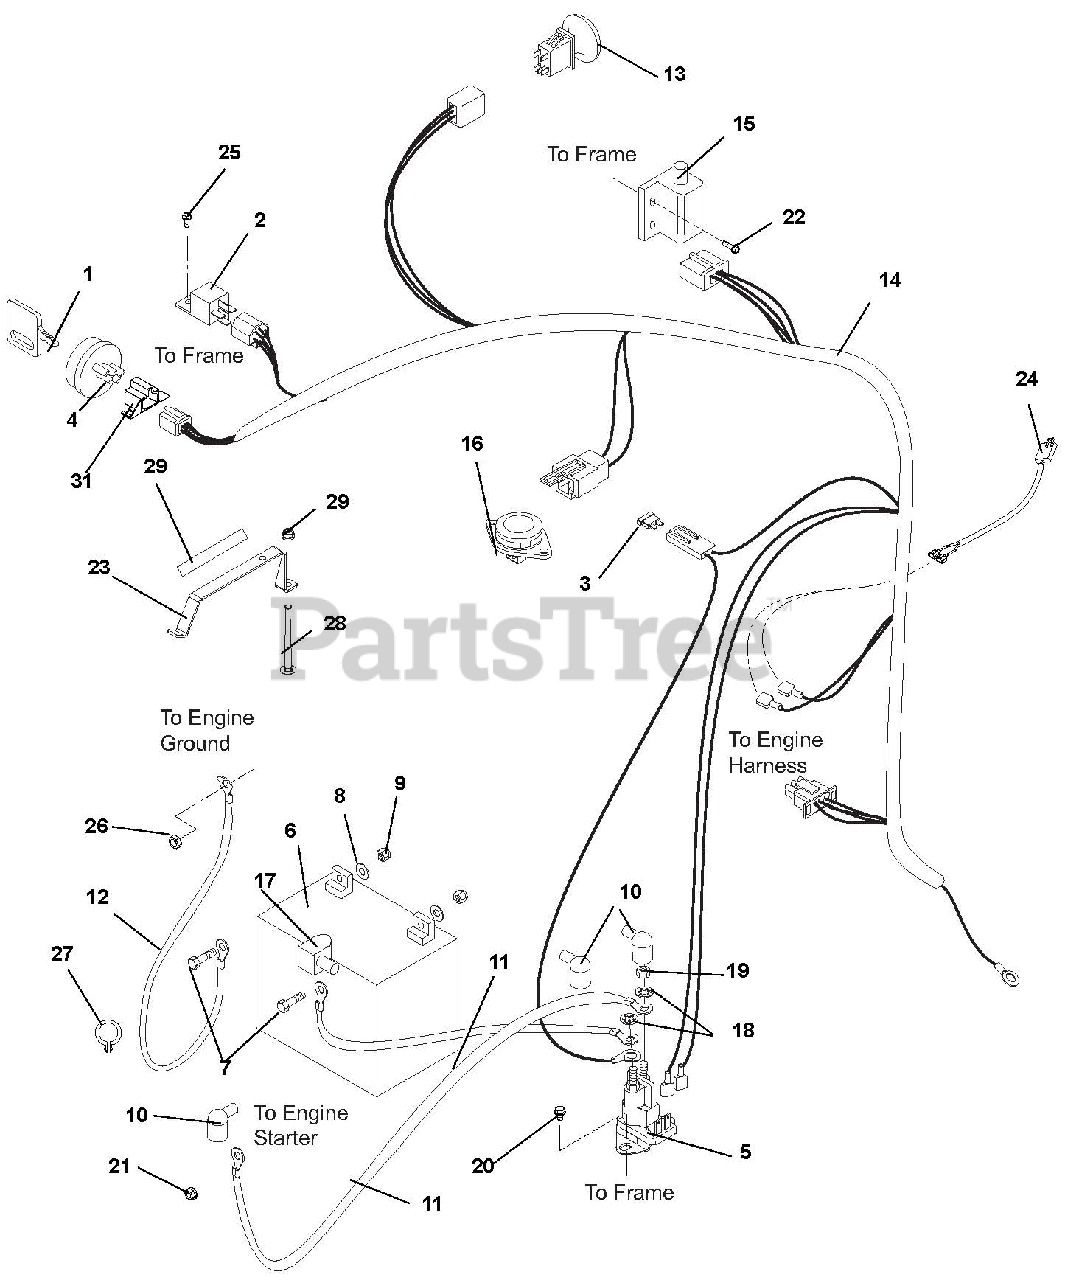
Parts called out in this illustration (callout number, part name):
1	KEY, 03290500 KEYSWITCH
1	KEY -W/CAP
2	RELAY
3	FUSE-25 AMP ATC TYPE
4	KEYSWITCH-IGNITION 3 POS
4	KEY SWITCH
5	SOLENOID, STARTER (SEALED)
6	BATTERY, 12V 12A-190CCA
7	@BLT-HEX .25-20X.75 GR5 YWZC
8	@WSHR-FL-STL.281X.62X.065 YWZC
9	NUT-KEPS .250-20
10	BOOT, EYELET TERMINAL
11	CABLE,POS W/2 1/4 RING 15.0 LG
12	CABLE, NEGATIVE 26" 6 GA.
13	SWITCH, CLUTCH (YELLOW)
14	HARNESS, ZOOM/ZT WIRE
15	SWITCH- DOUBLE POLE N.O./N.O.
16	SWITCH- SEAT
17	INSULATOR
18	@WSHR-LK-EXT.262X.502X.026YWZC
19	@NUT-LK-CTR .31-18 YWZC
20	@SCR-TAP .25-20X.37 HWH YWZ TR
21	@NUT-LK-TOP-FLG .25-20 YWZC
22	SCR- 12-14X.75 HX W/HD TEK ZC
23	HOLDDOWN, BATTERY, U1&190CCA
24	HARNESS, CLUTCH
25	@SCR-TAP 10-24X.50 HWH TR YWZC
26	@NUT-LK-CTR-JAM .375-16 YWZC
27	WIRE CLIP
28	@BLT-RDHDSQNK .25-20X4.50 G2YZ
29	@NUT-LK-NYL-FLG .25-20 YWZC
30	CABLE TIE LG 5-1/2
31	WIRE HARNESS, KEY SWITCH ADAPT
